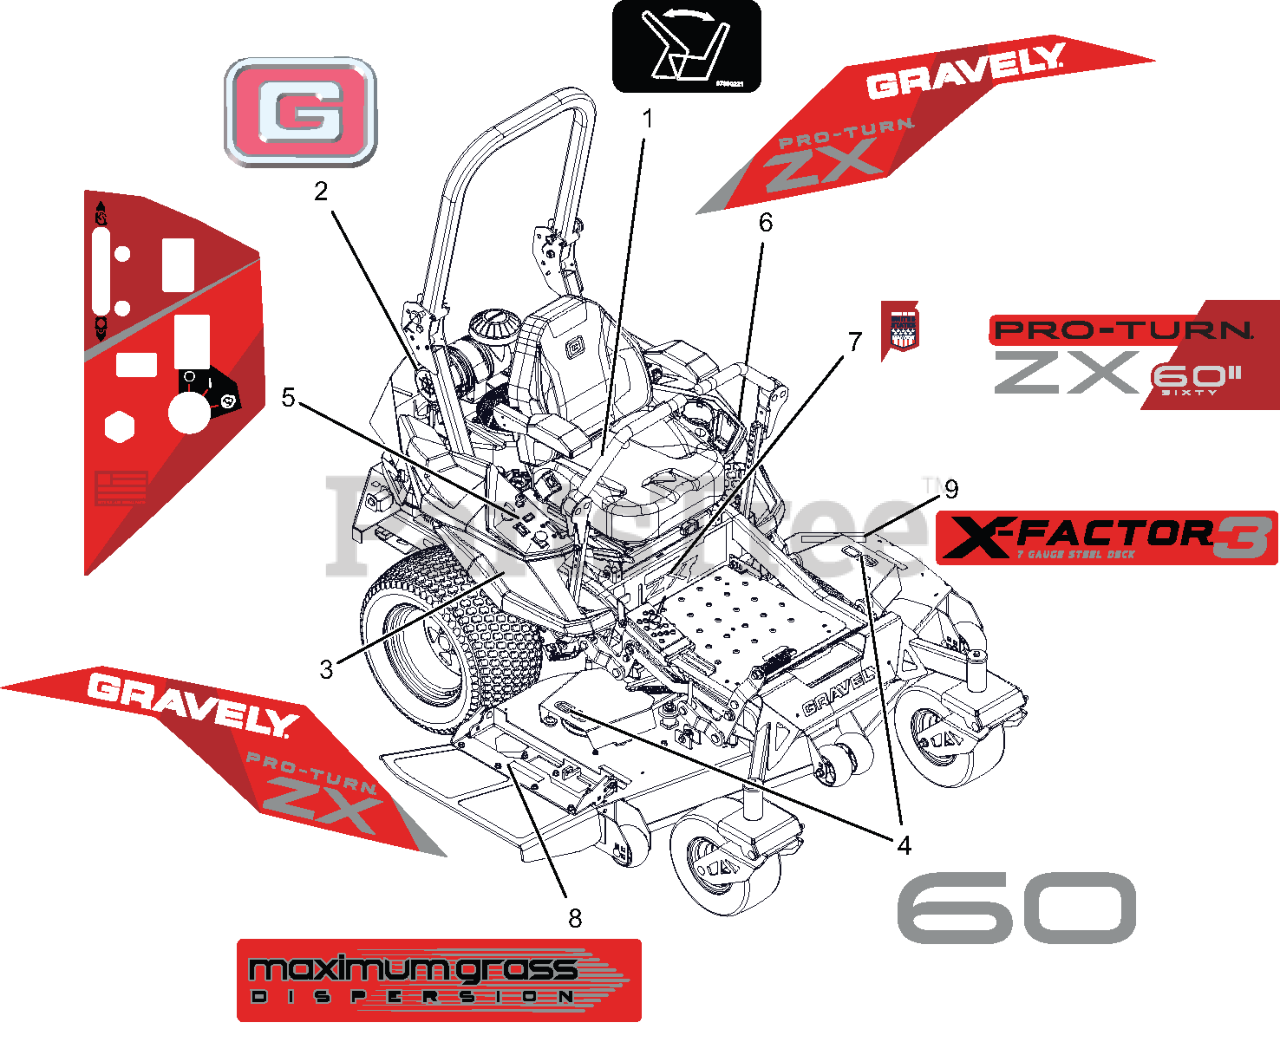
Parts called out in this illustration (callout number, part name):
1	DECAL - SEAT RELEASE
2	DECAL, GRAVELY BRAND
3	DECAL, FENDER RH - PTZX
4	DECAL, DECK - 60
5	DECAL, CONTROL PANEL
6	DECAL, FENDER LH - PTZX
7	DECAL, PTZX - 60
8	DECAL, DECK - MAX GRASS
9	DECAL, DECK - X-FACTOR 3 7 GAUGE
